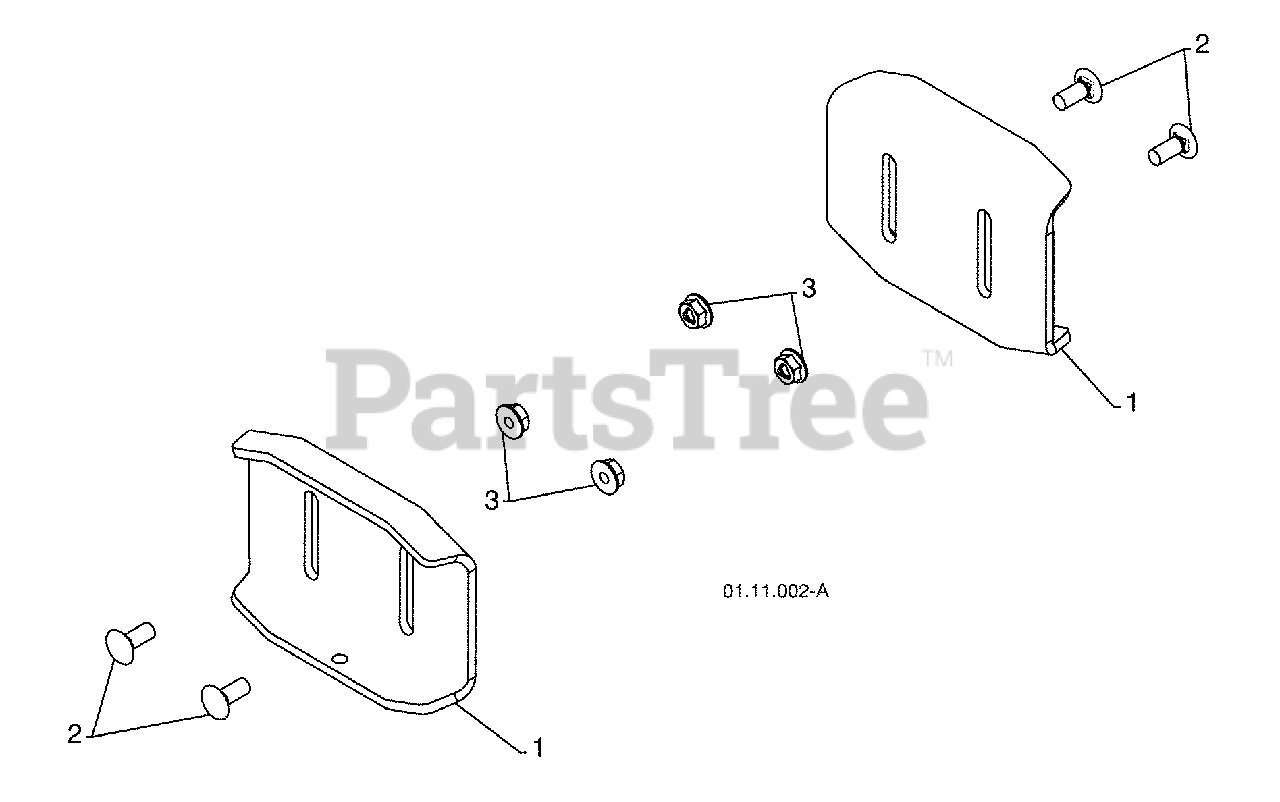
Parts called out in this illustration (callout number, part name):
1	SKID PLATE
2	CARRIAGE BOLT 5/16--18 X .750
3	NUT 5/16--18
